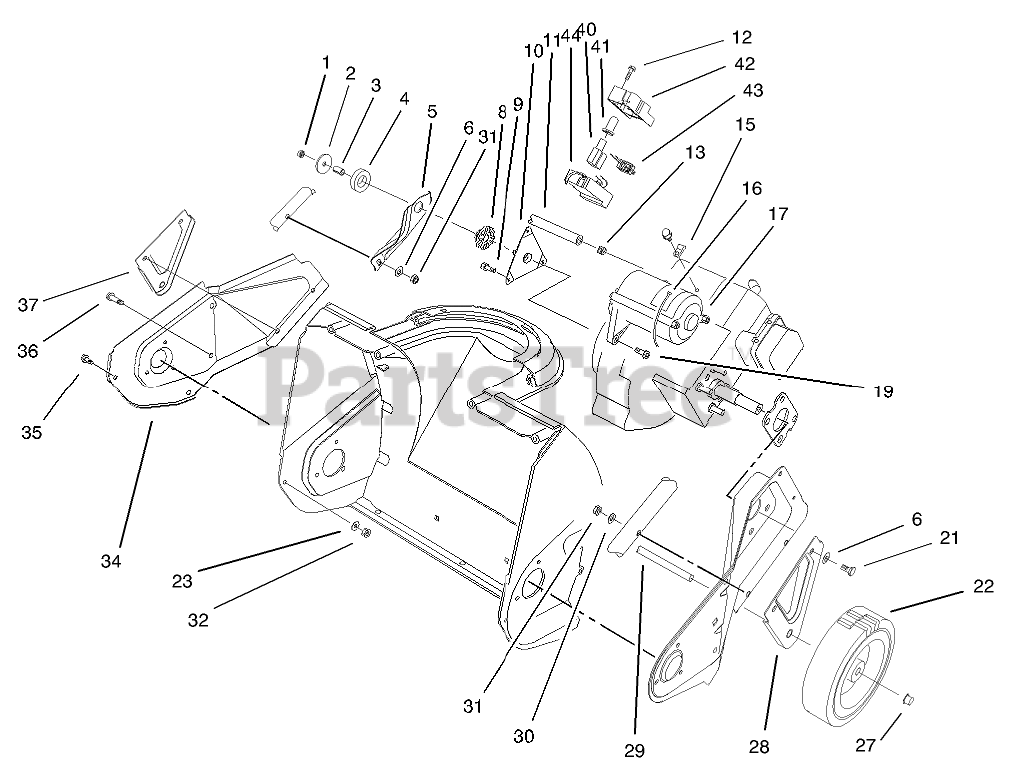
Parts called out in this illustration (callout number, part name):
1	NUT-LOCK, NI
2	WASHER-FLAT
3	SPACER-TUBULAR
4	RING-ISOLATOR
5	BRACKET-SUPPORT, ENGINE
6	WASHER-FLAT
8	BUSHING-ISOLATOR
9	SCREW
10	BRACKET AND STUD ASM
11	LINE-GAS
12	Screw-Plastite (only on: 38182)
13	CLAMP-HOSE
15	Clamp (only on:38182)
16	Tie-Cable (only on:38182)
17	Starter Motor ASM120 Volt] (only on:38182)
19	Screw-Mtg Torx (only on: 38182)
21	SCREW-HH
22	WHEEL
23	WASHER-FLAT
27	RETAINER-PUSH ON
28	BRACKET-WHEEL, LH
30	WASHER
31	NUT-LOCK, NI
32	NUT-LOCK, NI
34	PLATE-SIDE, RH
36	SCREW-PLASTIC
37	BRACKET-WHEEL, RH
40	Switch-Starter (onlyon: 38182)
41	Boot-Switch (only on:38182)
42	Switch-Cap Housing (only on: 38182)
43	Plug-Power (only on:38182)
44	Switch-Base Housing (only on: 38182)
